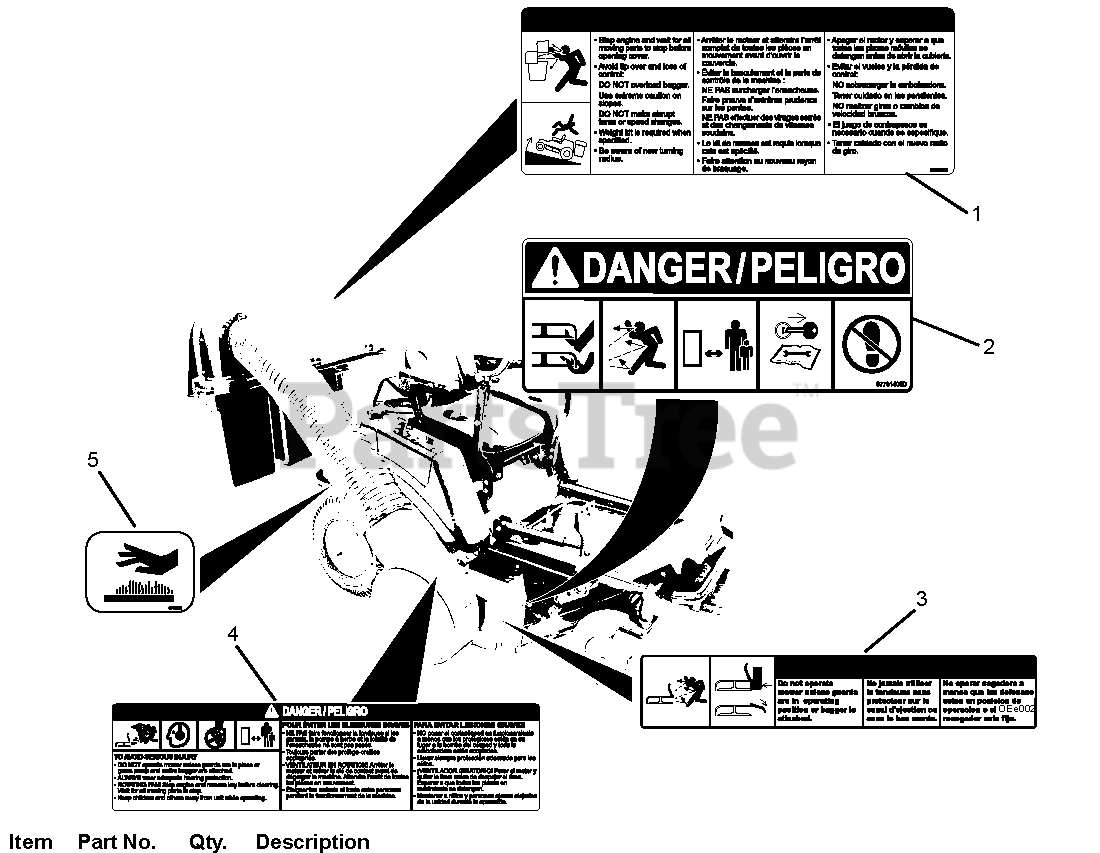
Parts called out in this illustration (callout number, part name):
1	Bagger Cover Decal
2	Mower Pan Danger Decal
3	Warning Decal
4	Grass Pump Caution Decal
5	Decal, Hot Surface
